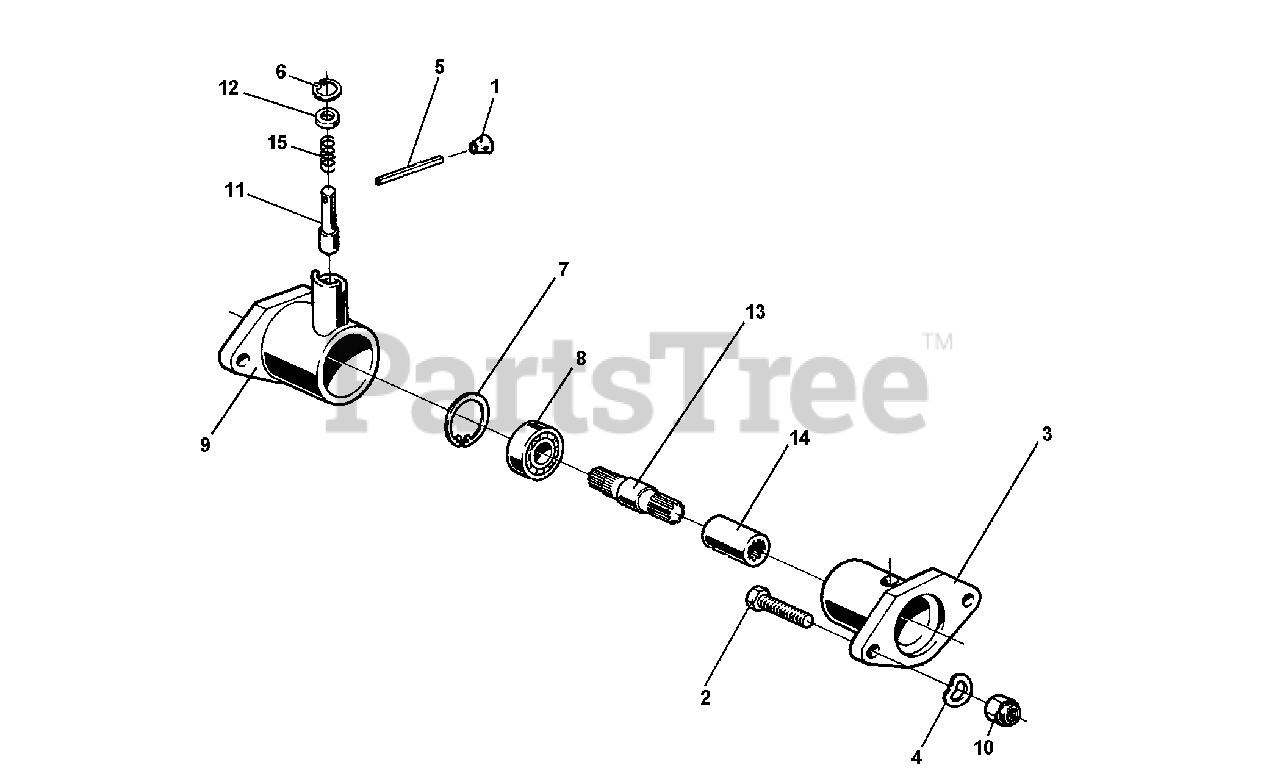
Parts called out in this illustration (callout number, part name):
2	SCREW TE M12 X 45 UNI
3	NUT, SELF LOCKING M12
4	WASHER, LOCK 13
5	LOCKING PIN 6 X 60
6	INSIDE CIRCLIP
7	CIRCLIP, INTERN. D 47
8	BEARING 20 X 47 X 14 6204 2RS ST
9	QUICK HITCH BODY
10	QUICK HITCH BUSH
14	BUSHING, GROOVED
15	FERRULE SPRING
